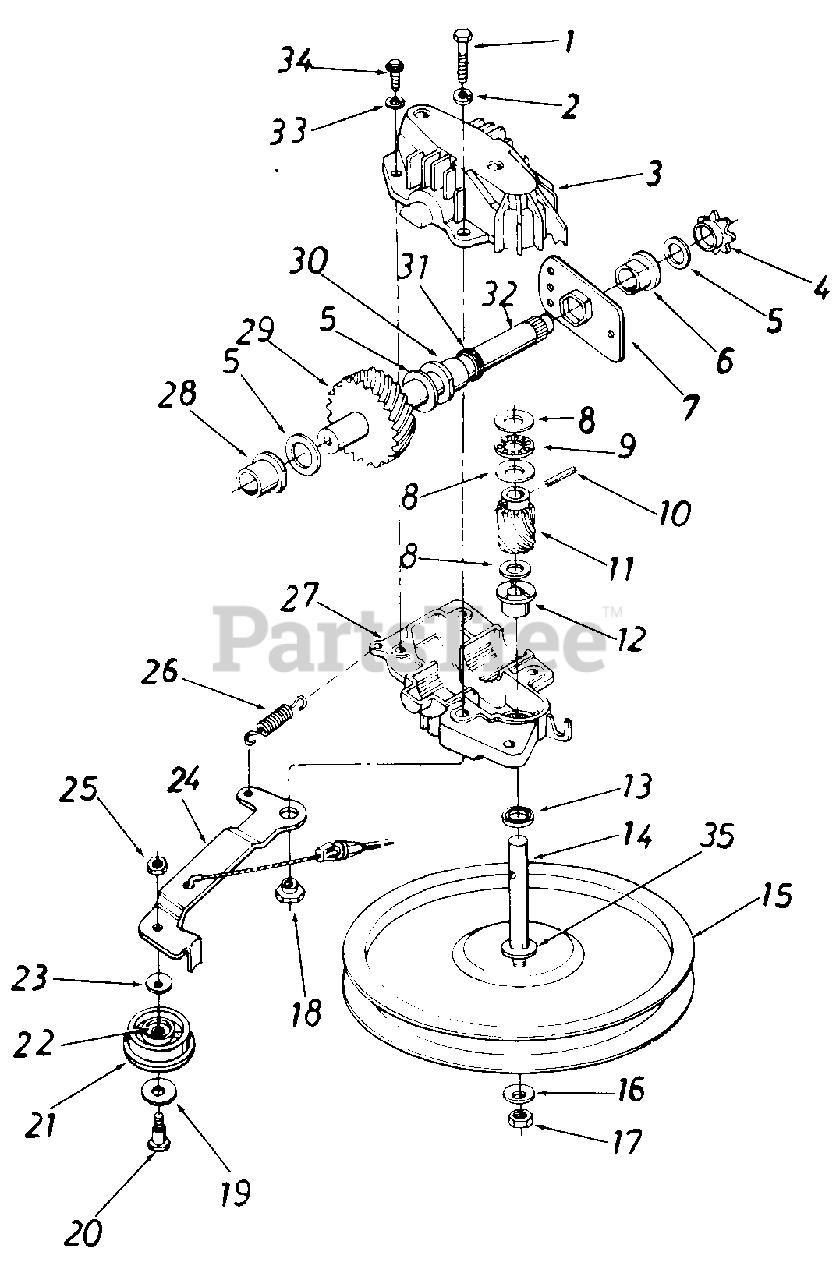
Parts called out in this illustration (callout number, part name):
1	Hex Bolt 1/4-20 x 1.25" Lg.
2	L-Wash. 1/4" I.D.
3	Upper Hsg. Half
4	#48 Sprocket 7 Tooth x 1/2 Pitch
5	Fl-Wash. 5/8" I.D. x .030
6	Hex Flange Brg. .631" I.D.
7	Hex Bearing Cup
8	Thrust Wash. .382" I.D. x .70" O.D.
9	Thrust Bearing .375" I.D. x .812" O.D.
10	Spring Pin Spir. 1/8" x .62" Heavy
11	11 Tooth Helical Gear
12	Flange Bearing
13	Oil Seal
14	Pulley-Transmission Shaft
15	Fl-Pulley 5.06" O.D.
16	Bell-Wash. .265" I.D. x 75"t
17	Hex L-Nut 1/4-28 L.H. Thd.
18	Shld. Spacer .375" Dia. x . 170t
19	Fl-Wash. .390" I.D. x 1.0"t
20	Shld. Bolt .375" Dia. x .40"t
21	Fl-Idler Plastic 1.50" Dia.
22	Needle Brg. .375" x .31t
23	Bell-Wash. .265" I.D. x 75"t
24	Idler Brk t. Ass y.
25	Hex Patch L-Nut 1/4-28 Thd.
26	Extension Spring 1.12" Lg.
27	Lower Hsg. Half
28	Flange Bearing .566 Dia.
29	33 Tooth Helical Gear
30	Flange Bearing .629 Dia.
31	Oil Seal .625 Dia.
32	Gear Sprocket Shaft
33	L-Wash. #10 I.D.
34	Hex B-Tap Scr. #10 x .62"
35	Hex Washer .26" x .88"t
